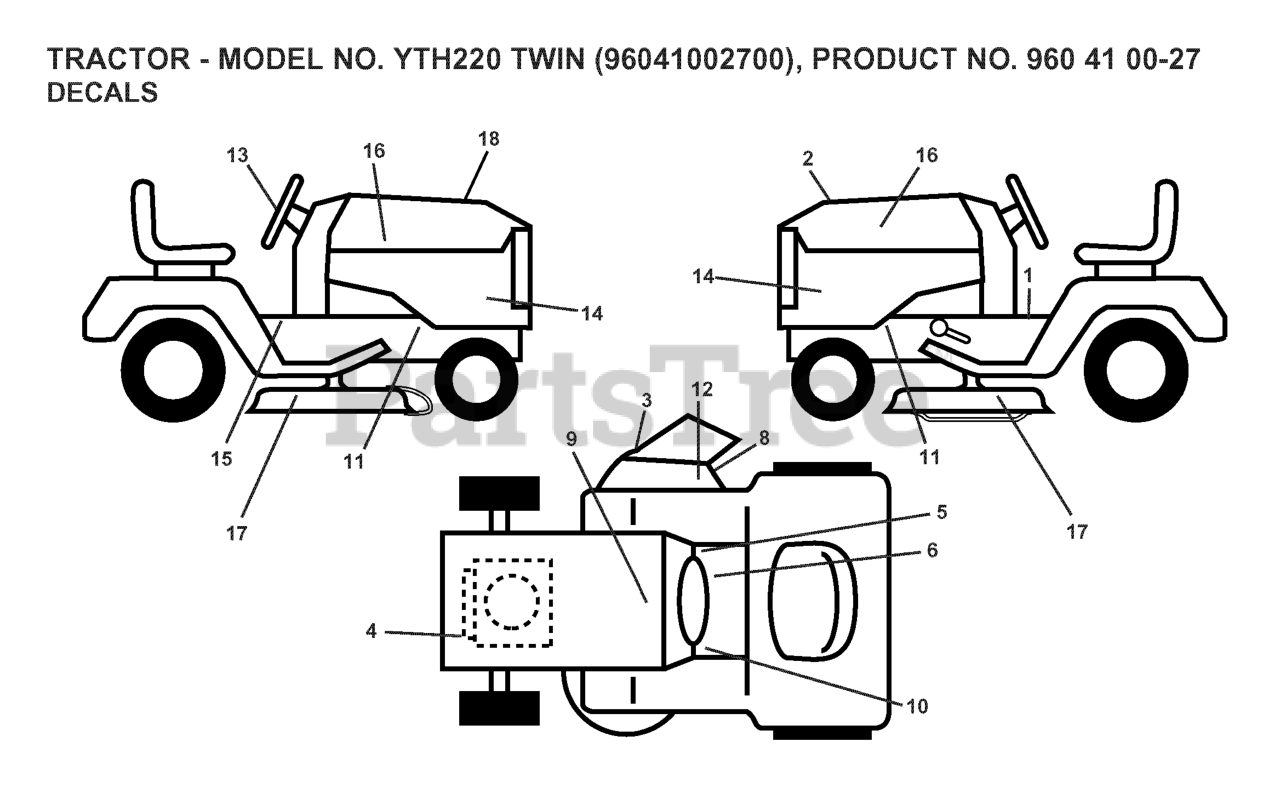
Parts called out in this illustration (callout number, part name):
1	LABEL
2	DECAL.HOOD.TOP.INSERT.
3	DECAL, DEFLECT WARNING
4	DECAL
5	DECAL PARK BRAKE
6	DECAL
8	DECAL.MOWER.SCH.48/54
9	DECAL BTRY SYMBOLS
10	DECAL
12	DECAL.INTERNATIONL.CUTFINGER
13	DECAL.WHEEL.STRG.LGN.H
14	DECAL PNL SD.
15	DECAL.FENDER
16	DECAL.HOOD.NAMELOGO.HUSQ
18	DECAL RPL KO
